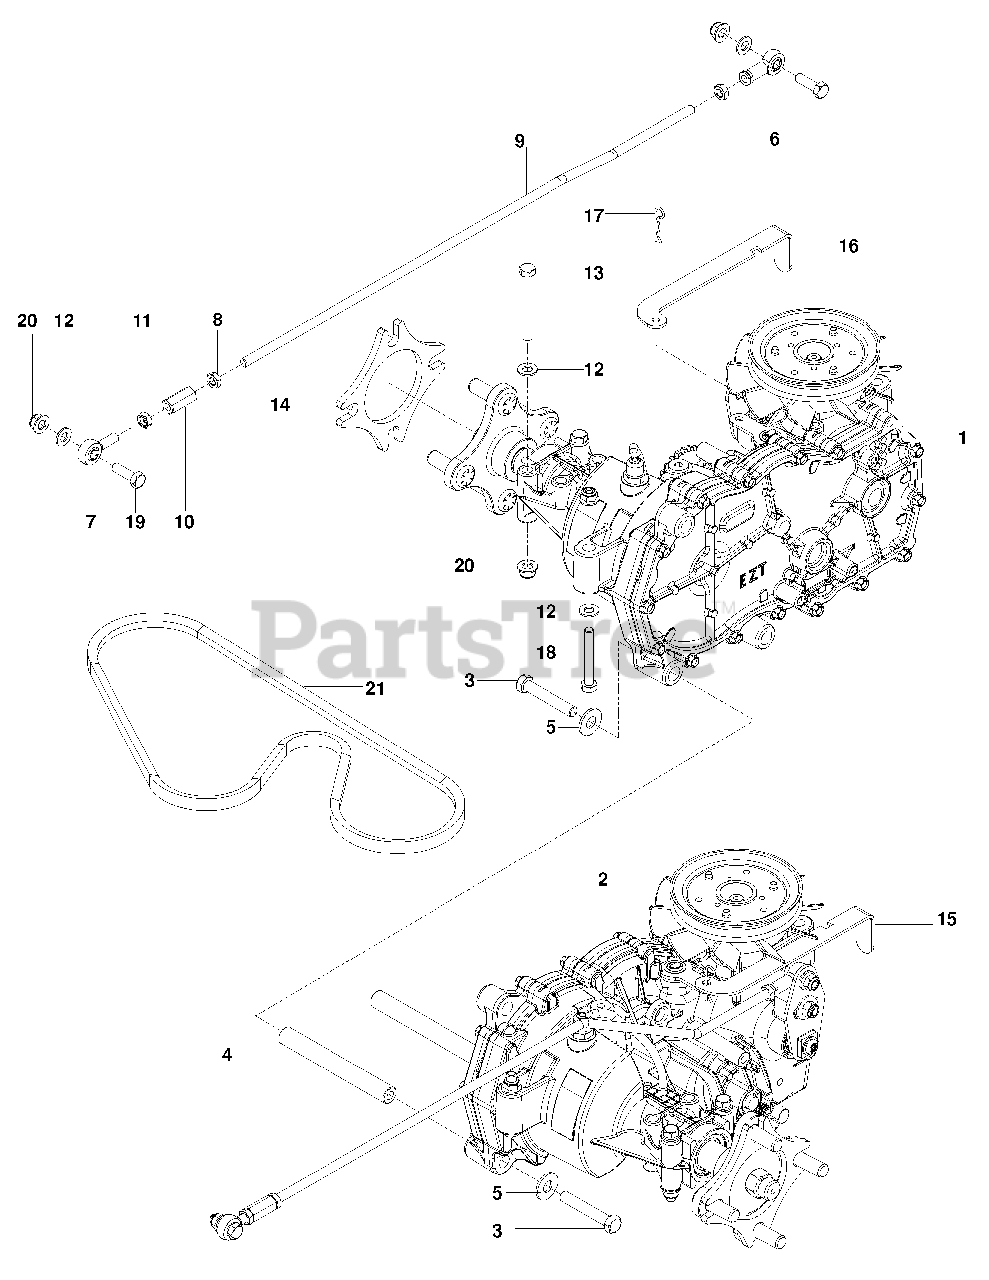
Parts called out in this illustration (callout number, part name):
1	HYDRO, RH
3	HCS 3/8-16 x 2 1/4
4	SPACER, HYDRO
5	WASHER 3/8 FLAT STD
6	ROD END, RH
7	ROD END, MALE LH
8	NUT 5/16-24 HEX JAM
9	ROD, CONTROL
10	ROD END COUPLER
11	NUT 5/16-24 HEX JAM LH
12	WASHER 5/16 SAE FLAT
13	HCS 5/16-18 x 2 3/4
14	SPACER, WHEEL
15	RELEASE HANDLE, LH
16	RELEASE HANDLE, RH
17	HAIRPIN COTTER
18	HCS 5/16-18 x 2 1/4
19	HCS 5/16-18 x 1
20	NUT 5/16-18 FLANGE NYLOC
